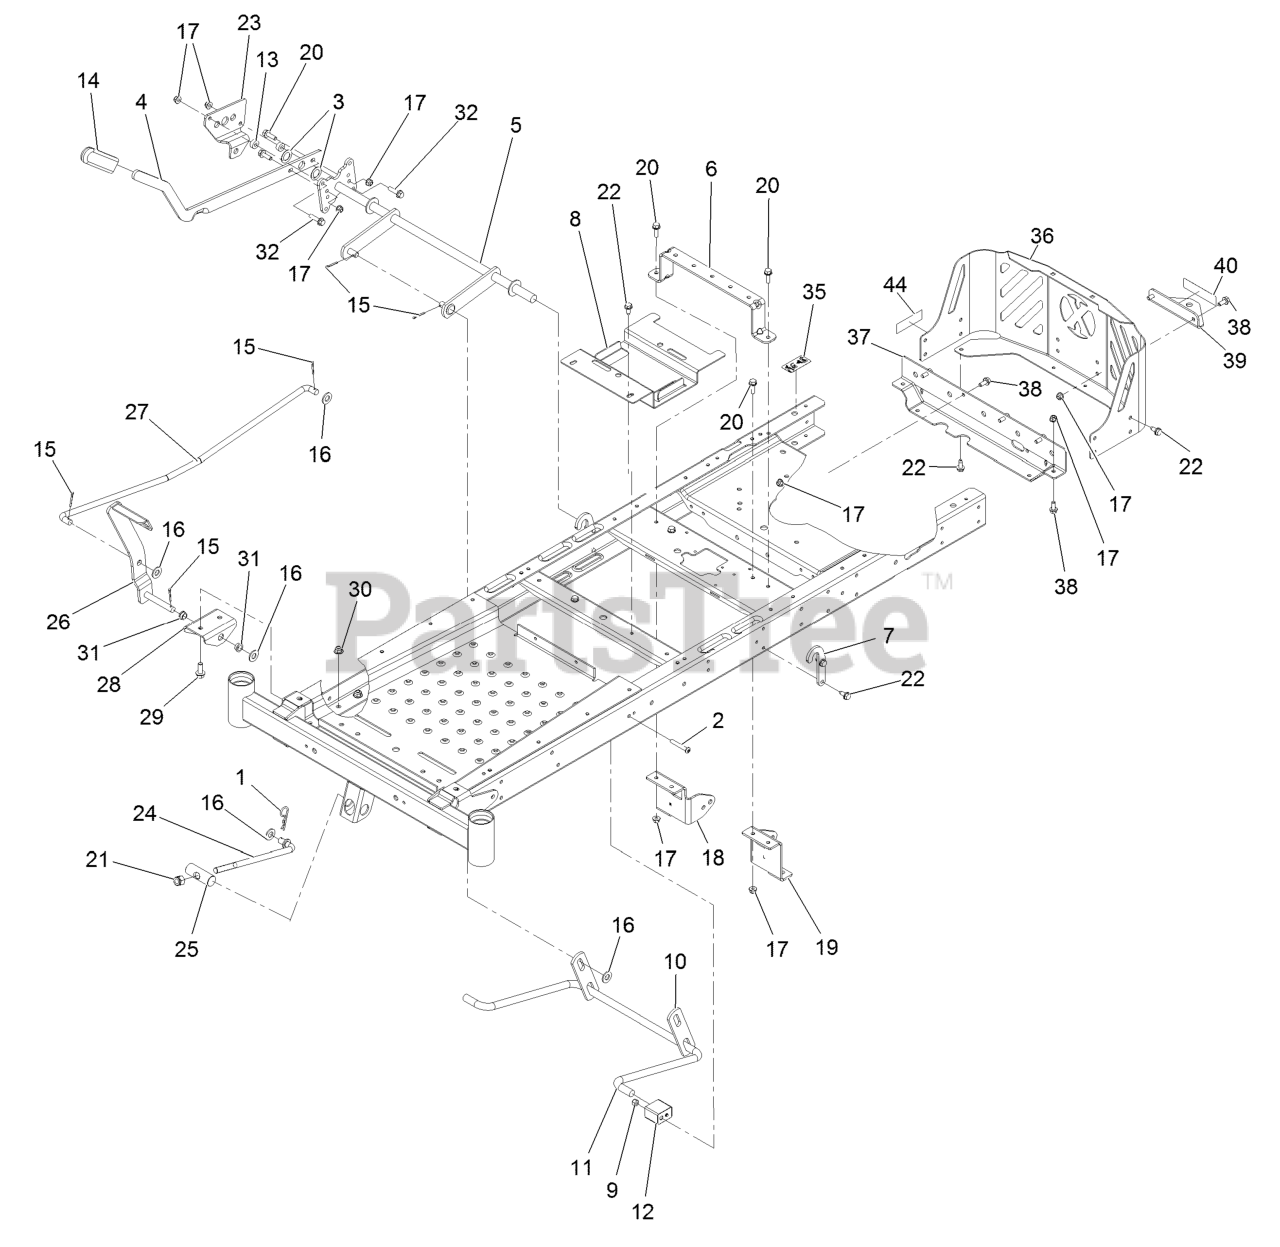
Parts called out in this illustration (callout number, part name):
1	PIN-COTTER
2	SCREW-HSBH
3	WASHER-THRUST
4	LEVER-LIFT
5	LIFT-DECK, NARROW
6	BRACE-SEAT, REAR (NARROW)
7	BRACKET-LIFT
8	BRACKET-BATTERY
9	NUT-LOCK, NI
10	LINK-LIFT
11	ARM-LIFT, REAR
12	BLOCK-PIVOT
14	GRIP-LEVER
15	PIN-COTTER
16	WASHER-FLAT
17	NUT-HF, NI
18	MOUNT-HYDRO, FRONT (RH)
19	MOUNT-HYDRO, FRONT (LH)
20	SCREW-HHF
21	NUT-HEX
22	Screw-HWH 5/16-18 X 3/4 Tf
23	PLATE-FOOTLIFT
24	ROD-MOUNT, DECK
25	PIN-PIVOT
26	PEDAL ASM
27	ROD-FOOTLIFT
28	BRACKET-FOOTLIFT
29	SCREW-HHF 3/8-16 X 1
30	NUT-HF, NI
31	BUSHING-FLANGE
32	SCREW-HHF
35	DECAL-BYPASS
36	GUARD-ENGINE, NARROW
37	CROSSMEMBER-REAR, NARROW
38	SCREW-HHF
39	BRACKET-HITCH
44	DECAL-ARRESTER, SPARK
